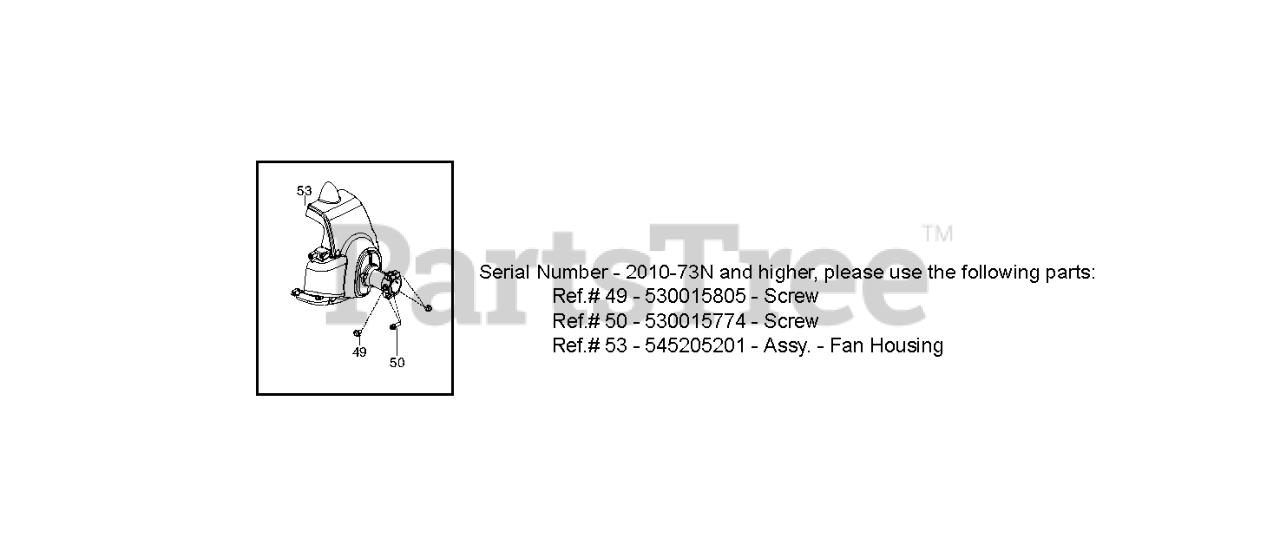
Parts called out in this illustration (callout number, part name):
49	SCREW-10-14 X 1/2 PLASTITE
50	SCREW-10-24 X 1" (UNC)
53	ASSY FAN HOUSING HVA 1"
